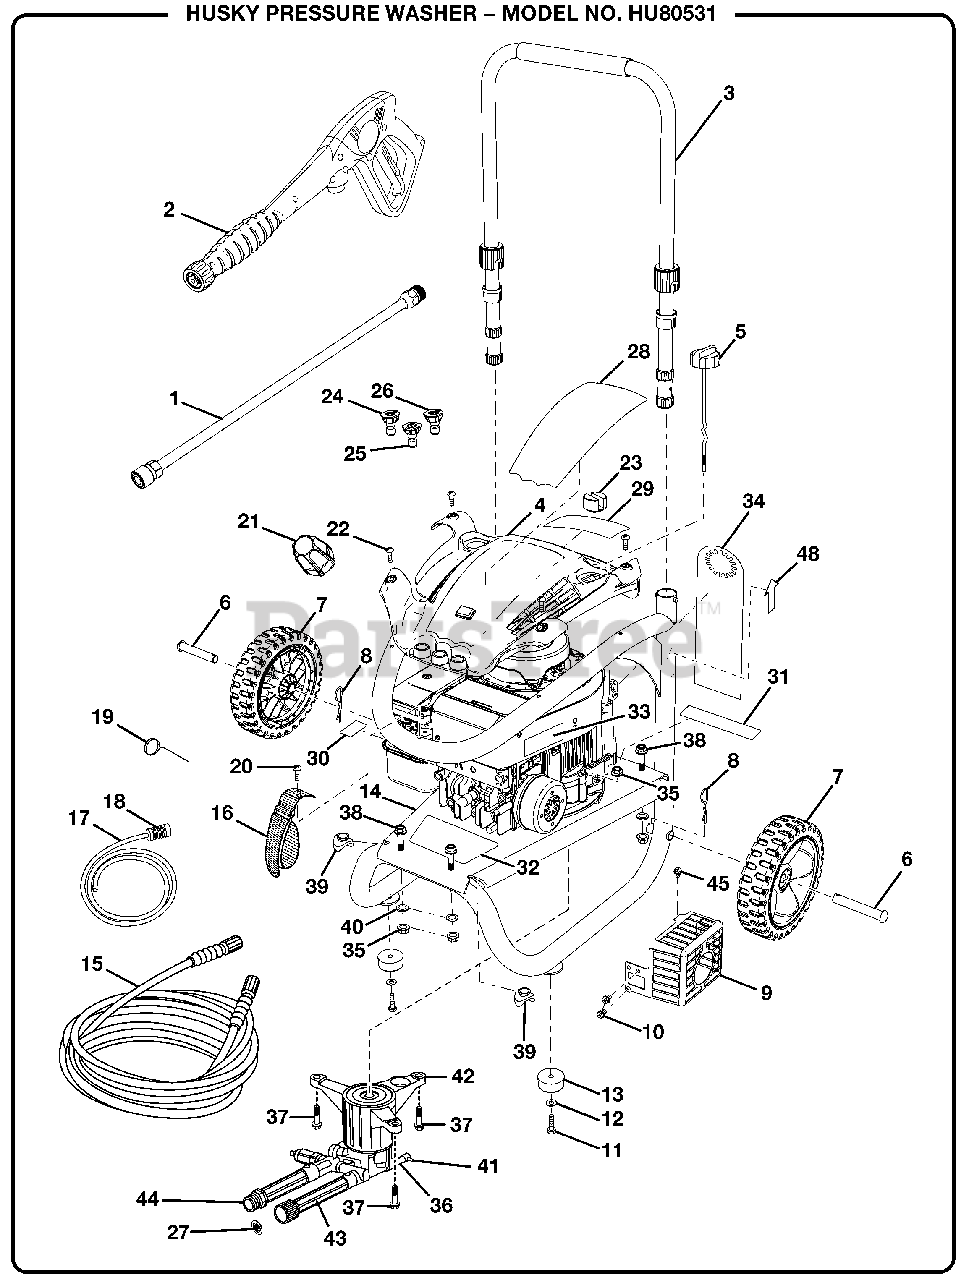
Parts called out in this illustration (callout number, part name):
1	Spray Wand Extension
2	Spray Wand
3	Handle Assembly
4	Engine Shroud Assembly
5	Oil Cap / Dipstick
6	Axle Assembly
7	Wheel Assembly
8	Hitch Pin
9	Muffler Guard
10	Screw (M5 x 8 mm)
11	Bolt (1/4-20 x 25 mm Hex Hd.)
12	Washer, 1/4 in.
13	Rubber Foot
15	High Pressure Hose (20 ft.)
16	Hook and Loop Strap
17	Injection Hose
18	Injection Hose Filter
19	Nozzle Cleaning Tool
20	Screw (12-14 x 13 mm)
21	Fuel Cap
22	Screw (12-14 x 15 mm)
23	Wand Holder
24	Nozzle, 0° (Red)
25	Nozzle, 25° (Green)
26	Nozzle, Detergent (Black)
27	Filter Screen
28	Logo Label
29	Quick Start Guide Label
30	Gas / Prime Label
31	Data Label
32	Danger Label
33	Hot Surface Warning Label
34	Danger Label (Hang Tag)
35	Lock Nut (M8)
36	Thermal Relief Valve
37	Bolt (M8 X 65 mm)
38	Bolt (M8 X 52 mm)
40	Washer (5/16 in.)
41	Plastic TRV Spout
42	Pump
43	Inlet Tube
44	Outlet Tube
45	Screw (M5 x 10 mm)
48	Press To Release Label
